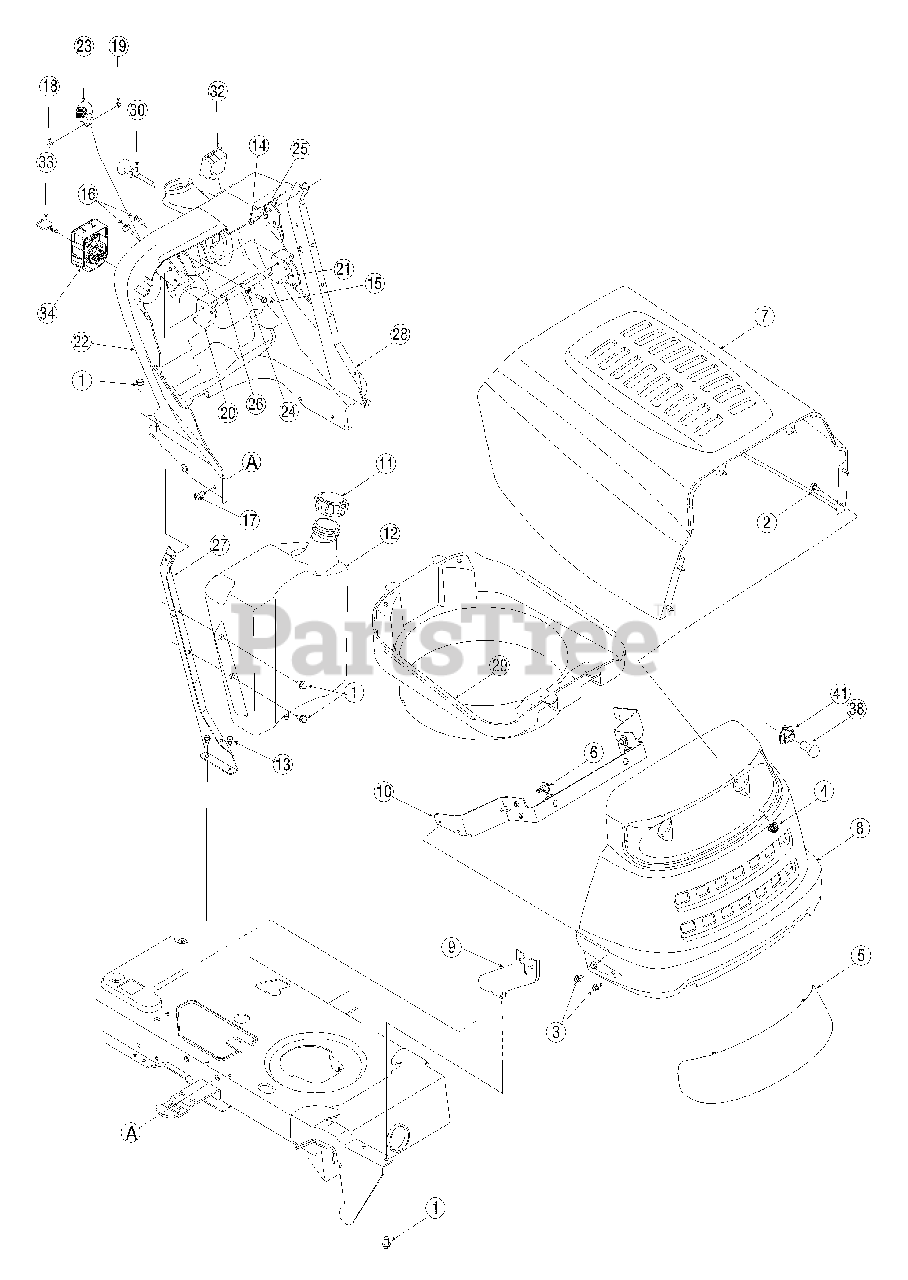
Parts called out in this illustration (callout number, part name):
1	Screw, 5/16-12, 0.750
2	Hex Head Cap Screw 1/4-20 x .620
3	Hex Washer Hd Tapp Screw 1/4-20 x .625
4	Flange Lock Nut 1/4-20
5	No. 1 Style Grill Lens
6	Shoulder Tapp Screw .43 x .29 5/16-18
12	3 Gal. Fuel Tank
13	Hex Washer Tapp Screw 1/4-20 x .500
14	Hex Washer Tapp Screw 1/4-20 x .750
15	Hex Washer Lock Screw 1/4-15 x .750
16	Screw, 1/4-14, 0.625
17	Screw, 5/16-18, 0.750
18	Screw, Machine, #8-32, 0.375
19	Nut, Hex, #8-32
20	Cruise Dash Lever Style 8&9
21	Brake Dash Lever Style 8&9
22	Dash Panel W/ Evac Style 8&9
23	Control Knob
24	Washer, Flat, .281 x .50 x .063
25	Washer, Bell, .265 x .75 x .062
26	Bent Lever Rod
29	No. 1 Style Hood Plenum
30	Choke Control
32	Hour Indicator Meter
33	Key
34	Key Module Switch
38	Miniature Lamp 12 V Socket
